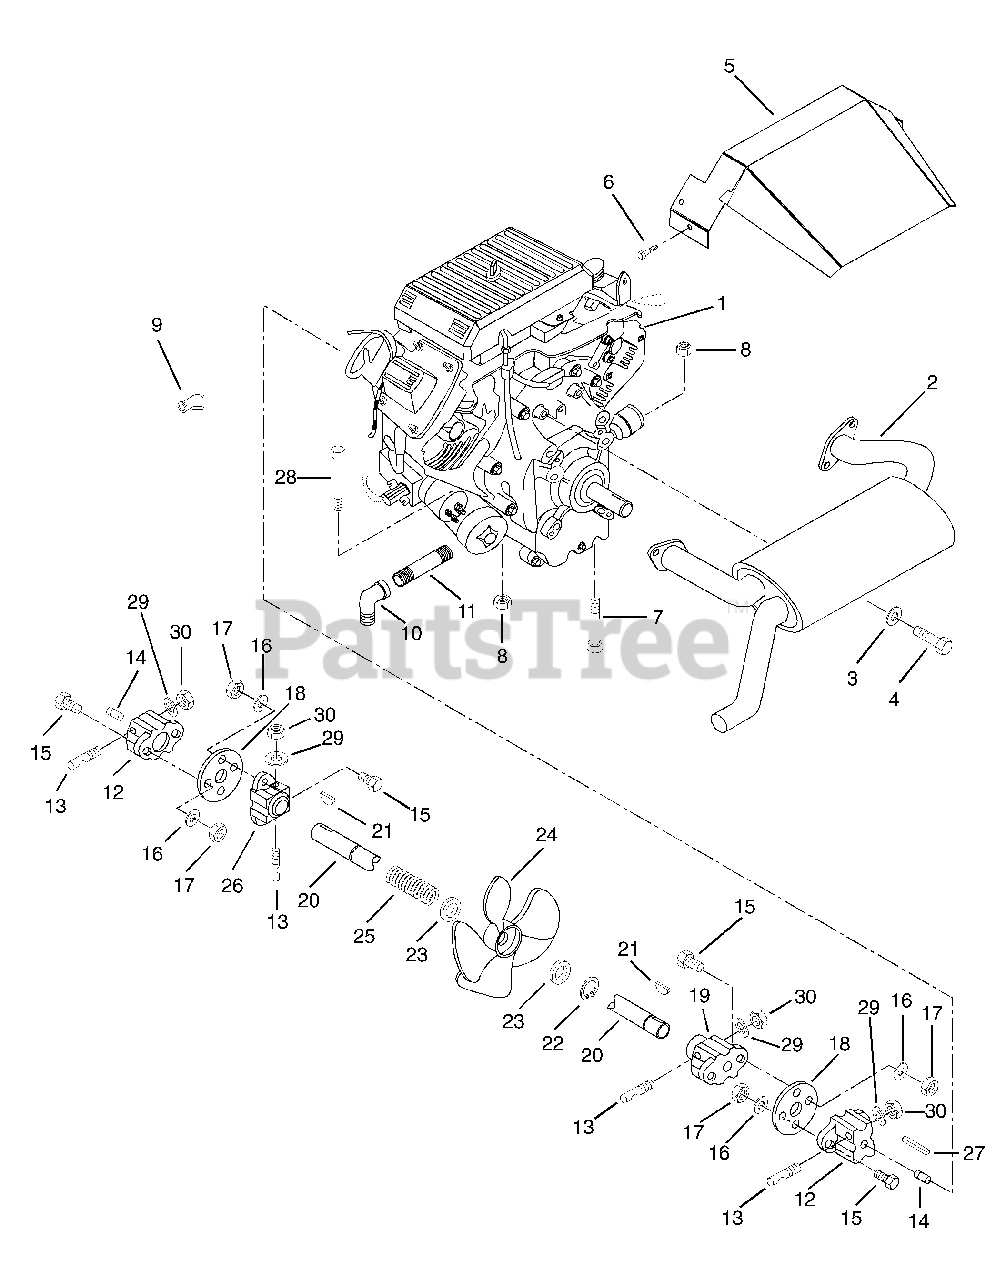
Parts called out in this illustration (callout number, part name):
1	ENGINE KOHLER CH22 PS-66540
2	MUFFLER - NELSON
3	WSHR-LK .438X.133 HVY YWZC
4	@BLT-HEX .44-14X1.00 GR5 YWZC
5	SHIELD, HEAT
6	BLT-HEX M6 X 1.0X12 LG
7	@BLT-HEX .38-16X1.75 GR5 YWZC
8	@NUT-LK-CTR .38-16 YWZC
9	BOOT, INSULATOR
10	ELBOW .375-18 NPTF
12	DRIVE HUB
13	LOCK STUD
14	PIN-GRV .313X.75 TP D
15	BOLT-HEX.31-18X.875 YWZC GR5
16	@WSHR-FL-STL.344X.688X.065YWZC
17	@NUT-LK-CTR .31-18 YWZC
18	SPACER COUPLING
19	DRIVE HUB- TWIN SHAFT
20	SHAFT, DRIVE
21	KEY-WDRF .188X.75X.313 SAE 9
22	RG-RTNG-EXT .750X.042
23	WSHR-HDND-THRST .758X1.23X.031
25	SG-COMP .120X.75X2.50 WLD48
26	DRIVE HUB
27	KEY-SQ .188X.75X.188
28	@BLT-HEX .38-16X1.50 GR5 YWZC
29	@WSHR-LK .38X.094 REG YWZC
30	@NUT-HEX .38-16 YWZC
